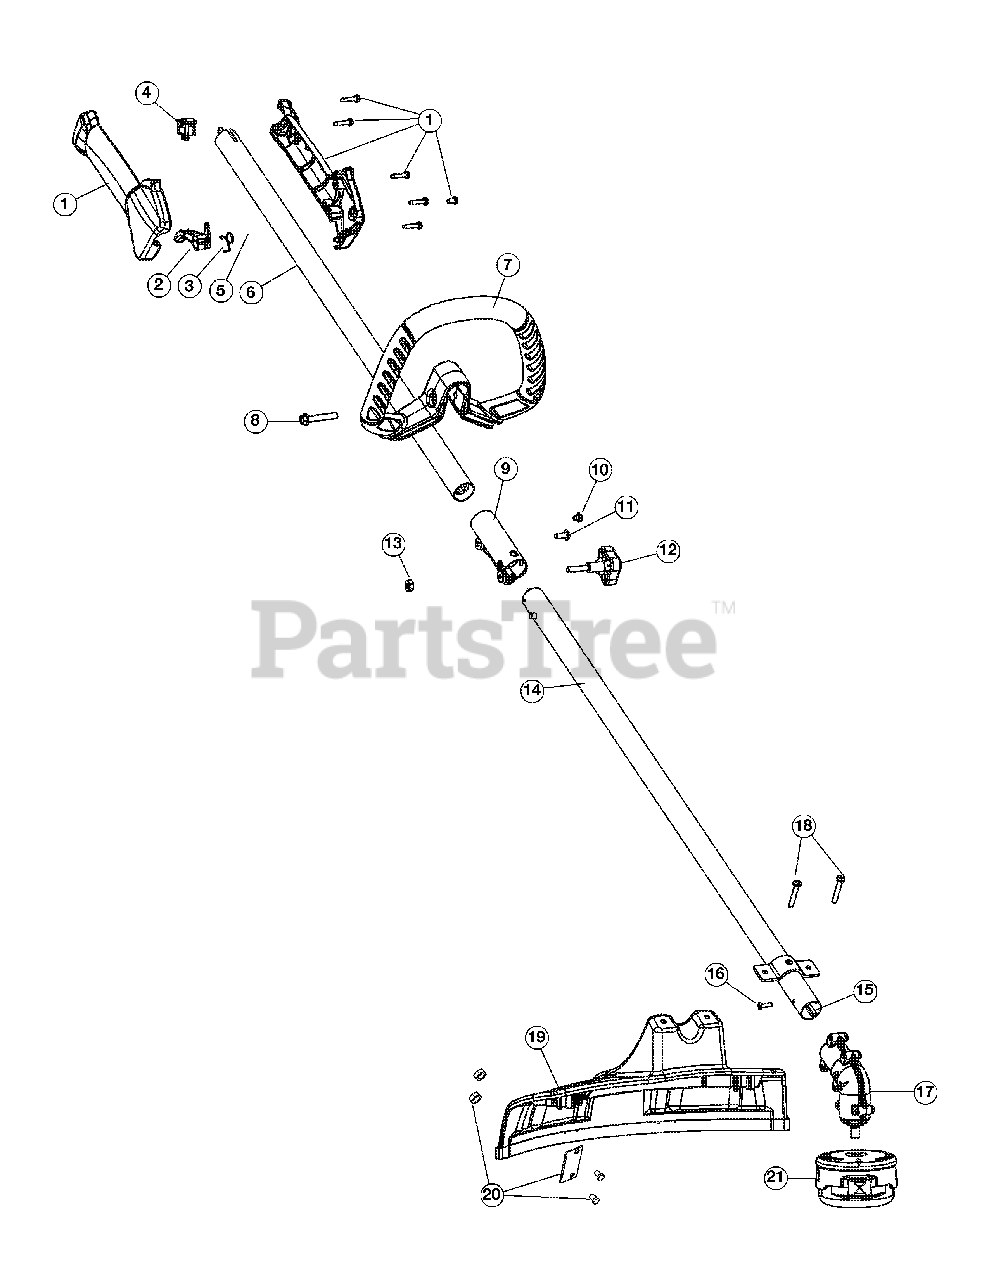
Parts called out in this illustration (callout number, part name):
1	Throttle Housing Assembly (Incl. Ref No. 2-4)
2	Throttle Trigger
3	Throttle Trigger Spring
5	Throttle Cable Assembly
6	Upper Drive Shaft Housing Assembly
7	Deluxe D-Handle Assembly (Incl. Ref No. 8)
9	Split Boom Coupler (Incl. Ref No. 10-13)
12	Adjustment Knob (Incl. Ref No. 13)
13	Knob Retaining Nut
14	Lower Drive Shaft Housing Assembly
15	Lower Flexible Drive Shaft
16	Anti-Rotation Screw
17	Gear Box Assembly (Incl. Ref No. 16)
18	Shield Mounting Screws
19	Shield Assembly (Incl. Ref No. 20)
20	Blade Assembly
21	Cutting Head Assembly
